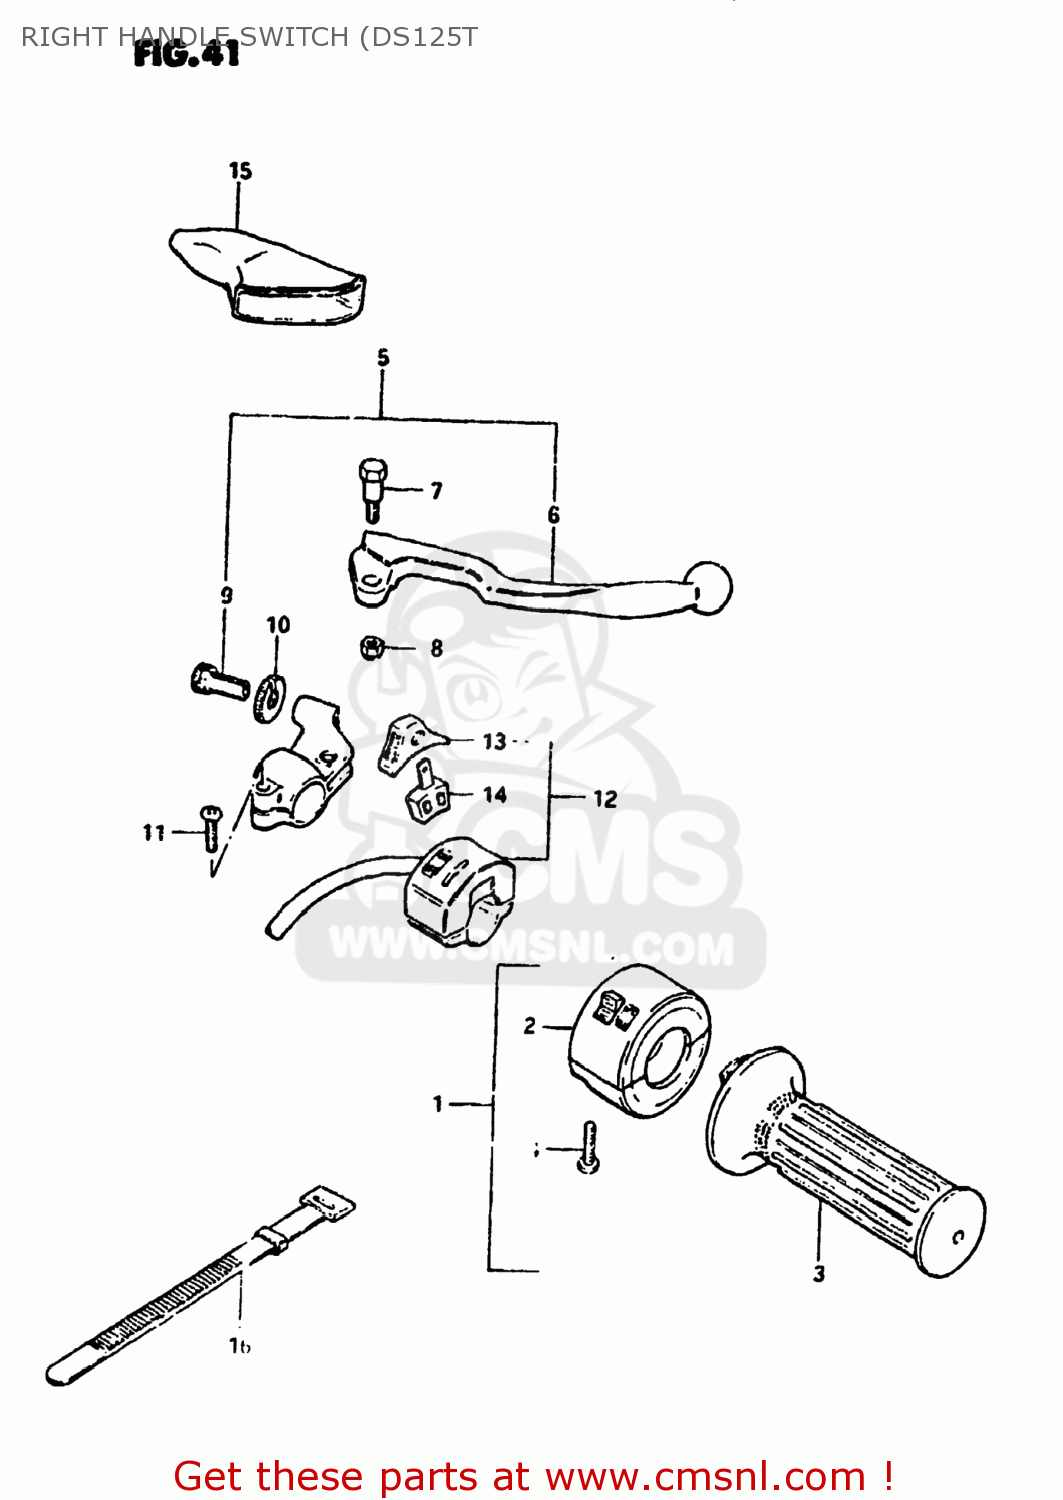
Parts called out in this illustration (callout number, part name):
1	CASE ASSEMBLY,THROTTLE
2	CASE ASSY,THROTTLE
3	GRIP,THROTTLE
4	SCREW
5	LEVER ASSEMBLY,BRAKE
6	LEVER,BRAKE
7	BOLT,LEVER
8	NUT 6MM
9	ADJUSTER,CABLE
10	NUT,CABLE ADJUSTER
11	SCREW
12	SWITCH ASSEMBLY,LIGHTING
13	KNOB,LIGHTING & DIMMER
14	BLOCK,LIGHTING/DIMMER
15	COVER,CLUTCH LEVER
16	CLAMP(L:120)
